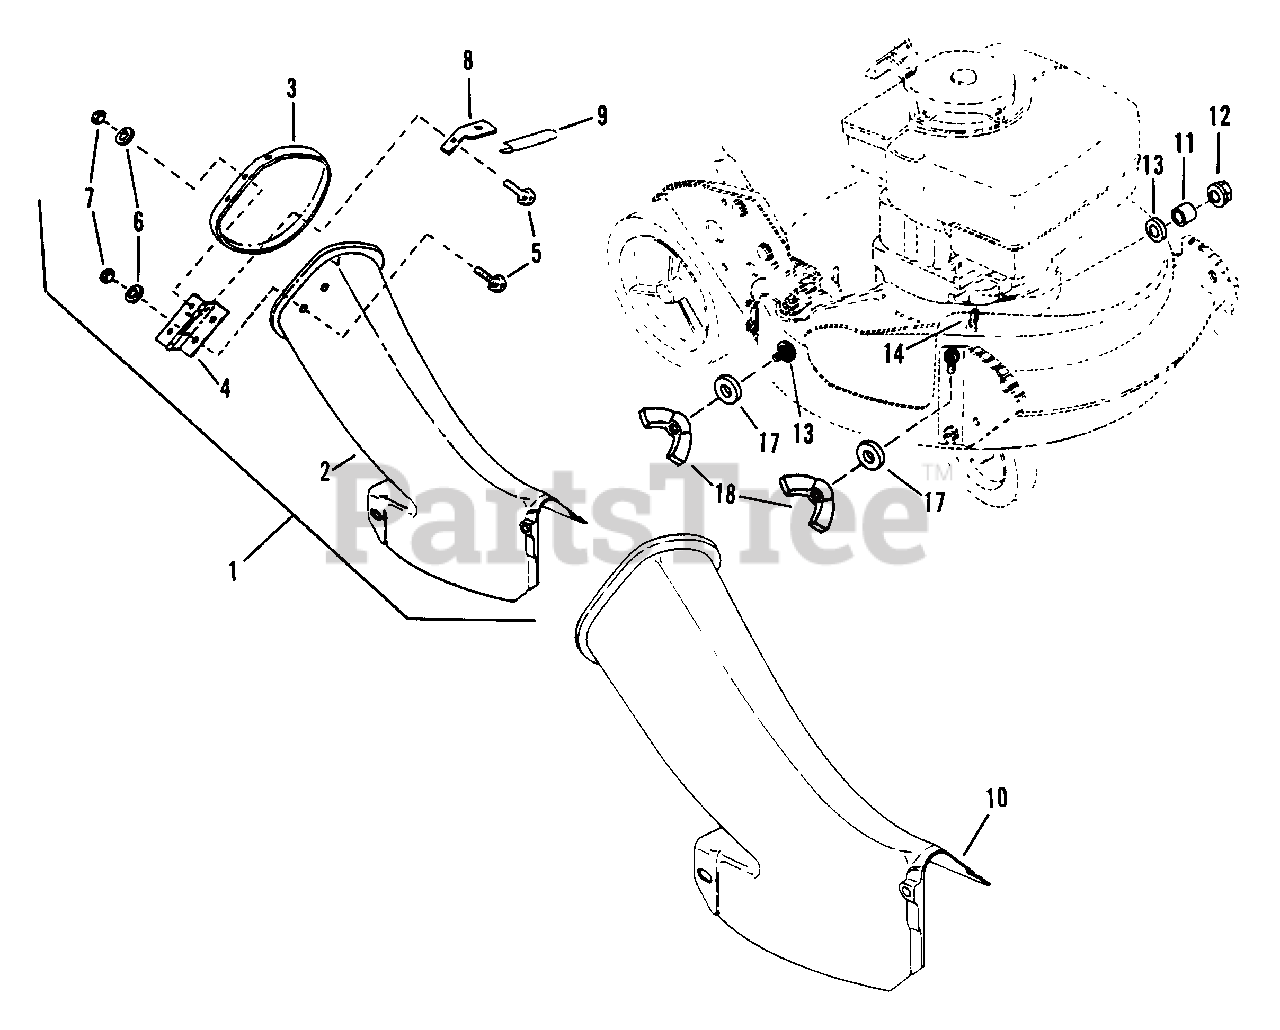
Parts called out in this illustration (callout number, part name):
1	ASSEMBLY, Bag Adapter & Cover
2	ADAPTER, Grass Bag
3	COVER, Bag Adapter
4	HINGE, Chute Cover
5	BOLT, 1/4-20 x 1/2" Short Neck Carriage
6	WASHER, 1/4 Internal Tooth Lock
7	NUT, 1/4-20 Hex
8	STOP, Cover
9	MOLDING, Trim
10	ADAPTER, Grass Bag
11	SPACER
12	NUT, 5/16-18 Hex Flange
13	RETAINER, 5/16 Bolt
14	BOLT, 5/16-18 x 3/4 Short Neck Carriage
17	WASHER, 5/16 Flat
18	WING NUT, 5/16-18
